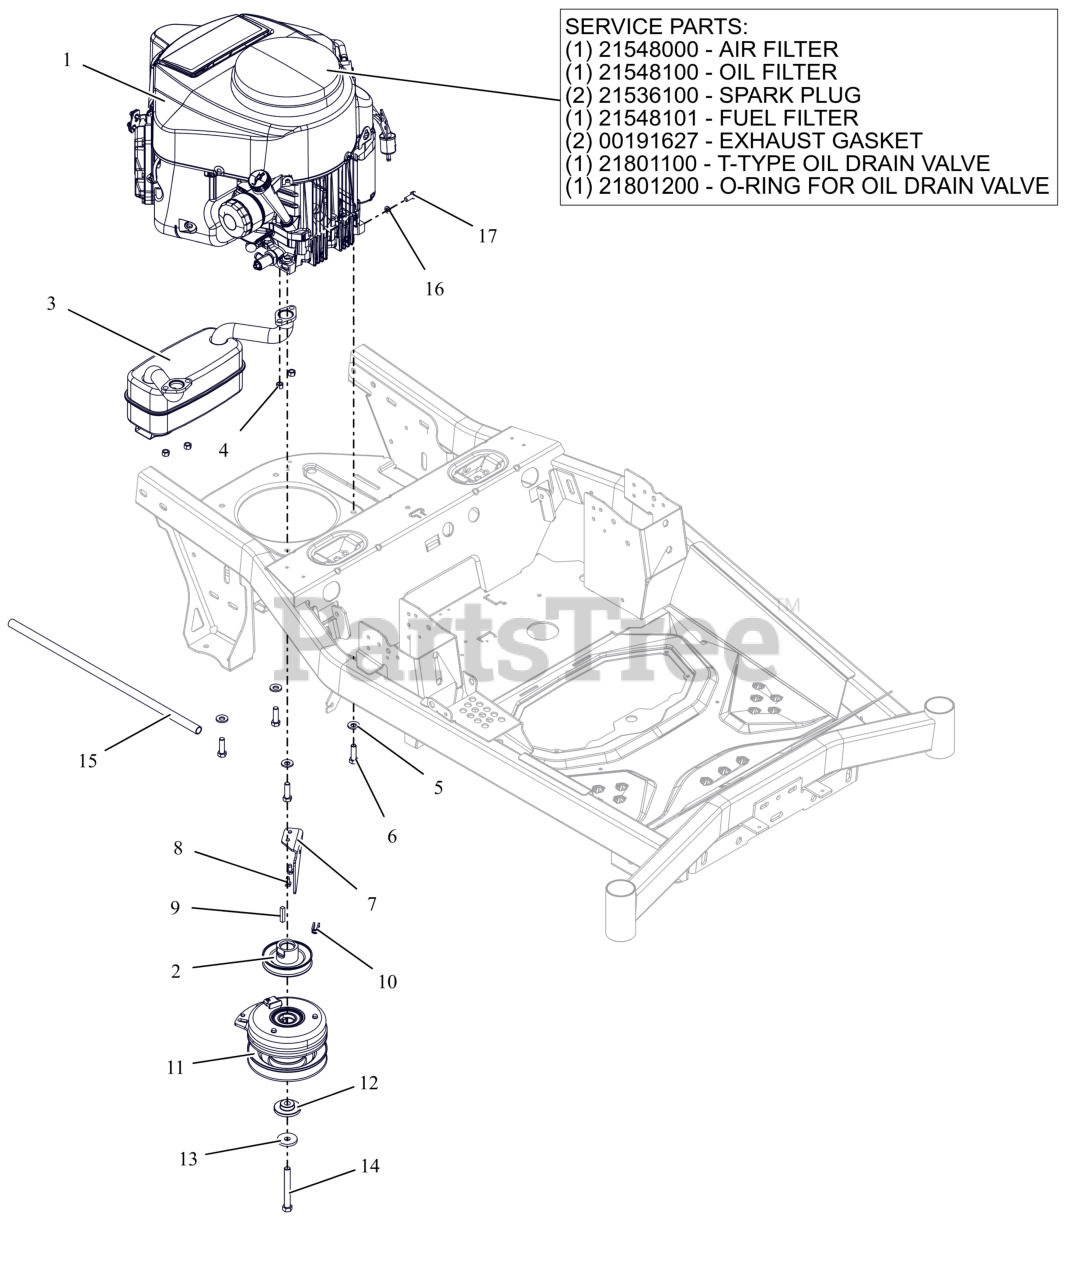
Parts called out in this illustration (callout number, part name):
1	ENGINE, KAWASAKI FR651V
1	AIR FILTER, KAWASAKI FR
1	OIL FILTER, KAWASAKI FR
1	PLUG, SPARK
1	FUEL FILTER-KAWASAKI FR
1	GASKET, MUFFLER S/O
1	VALVE- T-TYPE OIL DRAIN
1	O-RING- OIL DRAIN VALVE
2	WLDMT-PULLEY-4.831OD X1.003
3	MUFFLER - KAWASAKI
4	NUT-LK-TOP-FLG M8 ZCC
5	WASHER, 3/8" SPRING DISC
6	BLT, HEX .38-16X1.25 G5 ZCC NT
7	BRKT- CLUTCH STOP
8	SCR-TAP .25-20X.50 HWH ZCC
9	KEY-SQ .25 X 1.25 X .25 SAE
10	BSHG, CLUTCH
11	CLUTCH, WARNER-IXR-18211
12	BSHG-FLG .469X1.06X.574X2.0
13	WASHER, 7/16" SPRING DISK
14	BLT- HEX .44-20X3.50 G8 ZCC NT
15	HOSE- OIL DRAIN
16	WSHR,LK-REG .312X.078 ZCC
17	BLT, HEX M8-1.25X20 G8.8 ZCC
